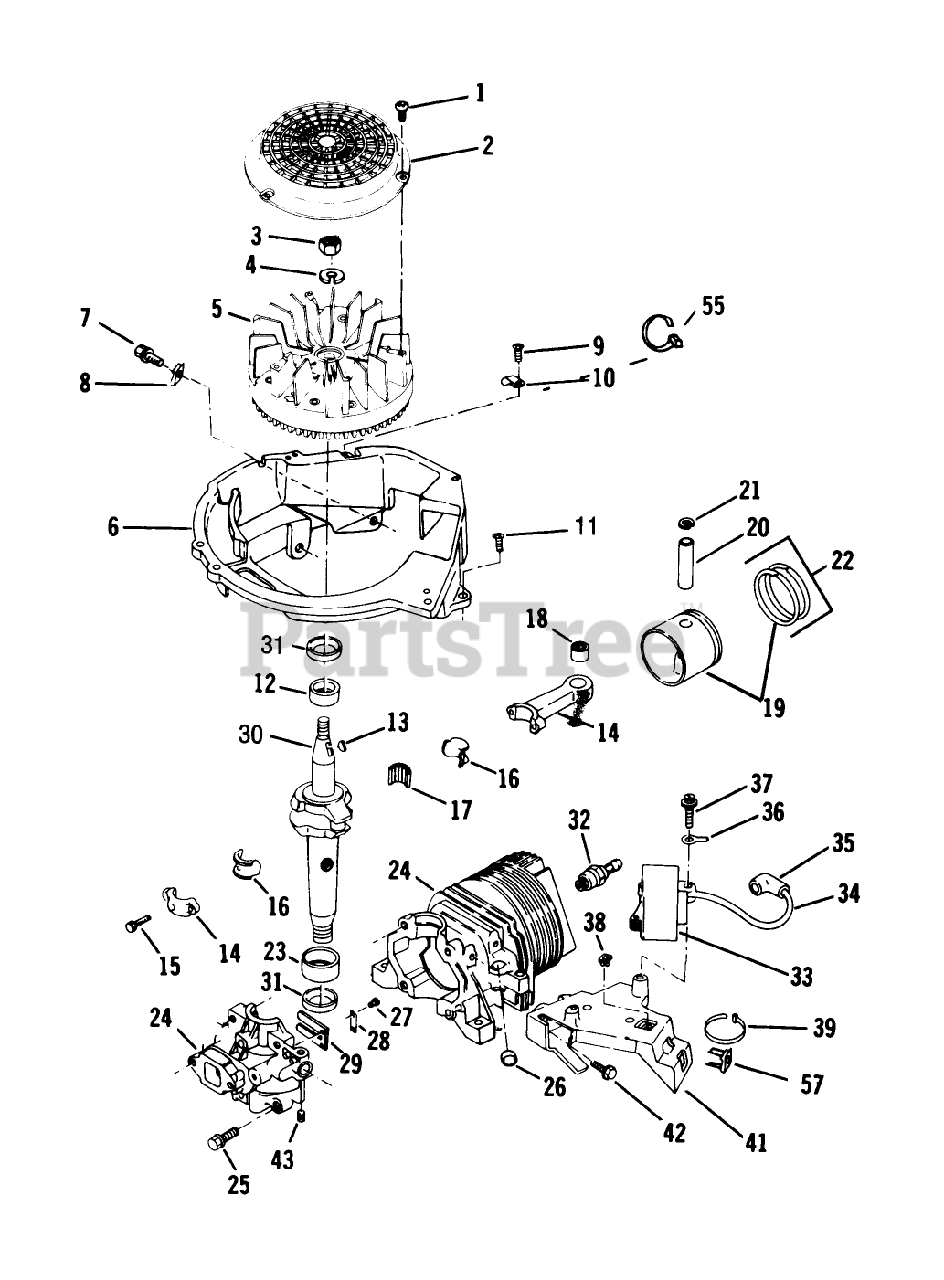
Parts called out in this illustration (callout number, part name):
1	SCREW F
3	NUT
5	FLYWHEEL ASSY F
7	SCREW-SEMS
9	SCREW F
11	SCREW F
12	BEARING V
13	KEY
15	SCREW-HSH
16	LINER ASM
18	BEARING AY F
21	RING-RETAINING
23	BEARING V
25	SCREW S
26	PLUG-CORE VF
27	SCREW-HH
28	PLATE-BACKUP, REED
31	SEAL-OIL
34	HT LEAD&COVER XEV
36	TERMINAL S
38	NUT-CLIP
44	NUT-CLIP
